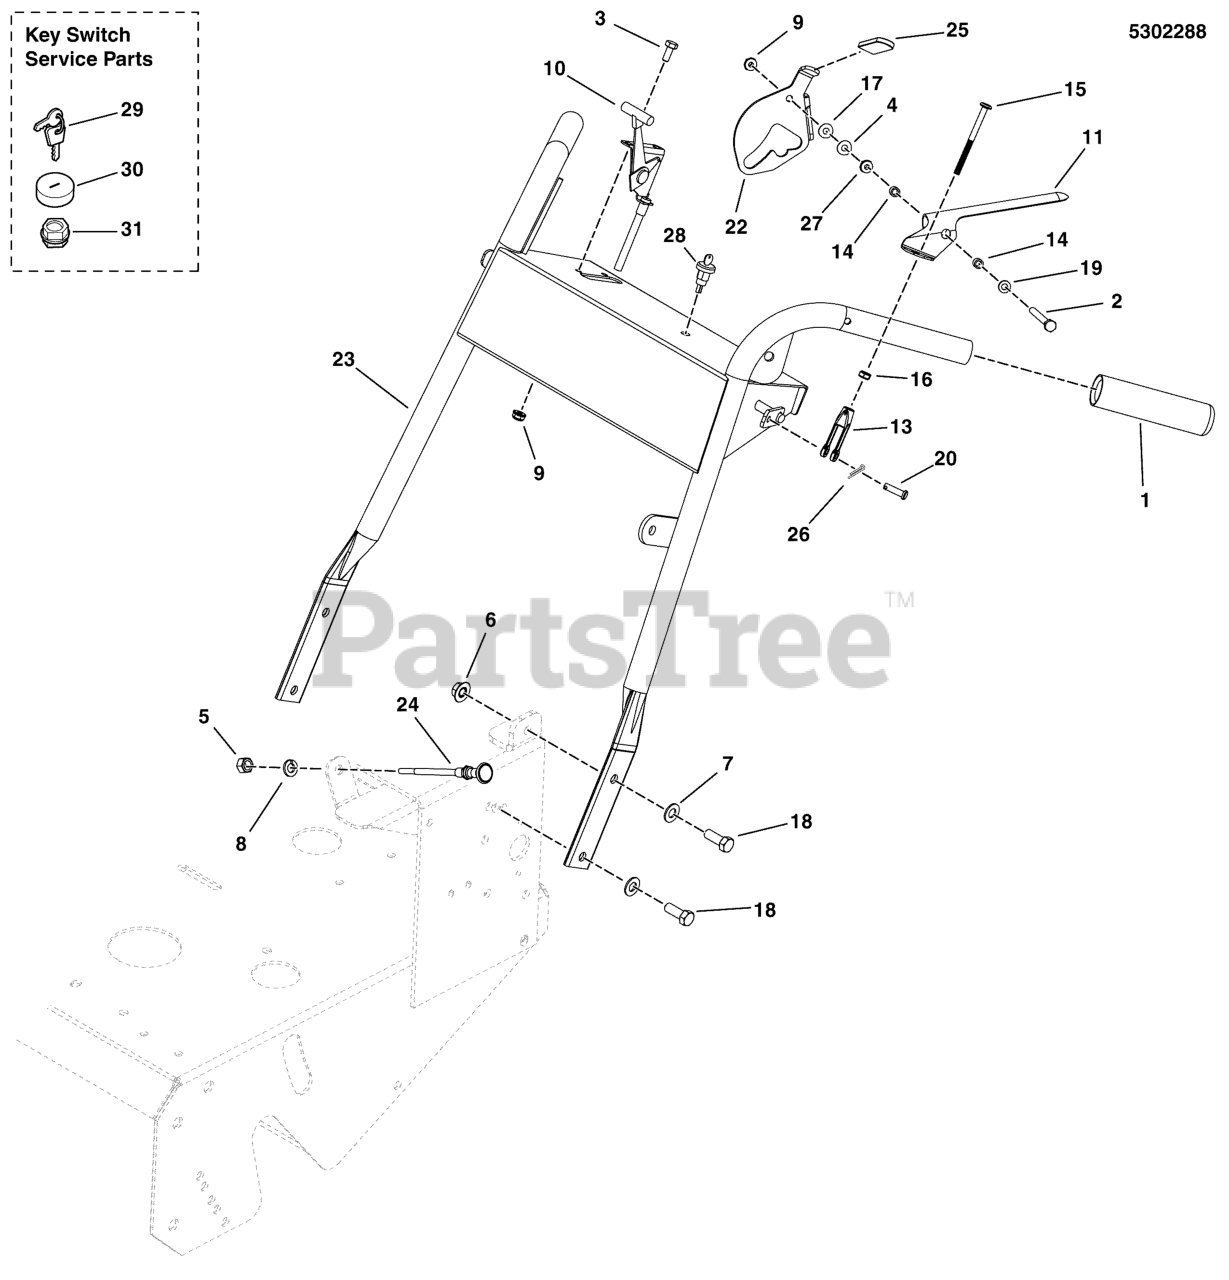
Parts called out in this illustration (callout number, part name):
1	GRIM, FOAM, .940" ID X 4.62" X .187", BLK
2	BOLT, HEX, 1/4-20 X 2-3/4, TFL, GD5, CZ
3	HHCS, 1/4-20 X 0.625, GR5, ZINC/CLEAR
4	WASHER-0.250(0.26IDX0.84ODX.12THK) YEL
5	NUT, 3/8-24 HEX
6	NUT, 3/8-16 HEX NYLOCK FLANGE
7	WASHER, 3/8 SAE
8	WASHER, 3/8 SPLIT LOCK
9	NUT, 1/4-20 HEX NYLOCK FLANGE
10	CABLE, THROTTLE CONTROL, 48"
14	SPACER, .265 X .375 X .25, CZ
15	ROD, OPC LINK, CCW
16	HN, 1/4F GR5 YZ
17	WASHER, WAVE, .31 X .70 X .01, SS
18	BOLT, 3/8-16 X 1" GD5 CZ
19	WASHER, 1/4 SAE
20	PIN, CLEVIS, 1/4 X 7/8, PLATED
22	THUMB LOCK LEVER, LH - BLK
23	WELD, HANDLE BAR, SW5 - RED
24	CABLE, CHOKE CONTROL, 35.25" DETENTED
25	GRIP, 1/8X5/8X1-1/2, BLK VINYL, RD END
26	SCREW, #10-24 X 3/4 ROUND PHILLIPS
27	NUT, 1/4-20 HEX SIDE LOCK
28	SWITCH, IGNITION, 2 POST
29	KEY, IGNITION MOLDED SET
30	COVER, PLASTIC, SNAP ON
31	PLASTIC NUT
